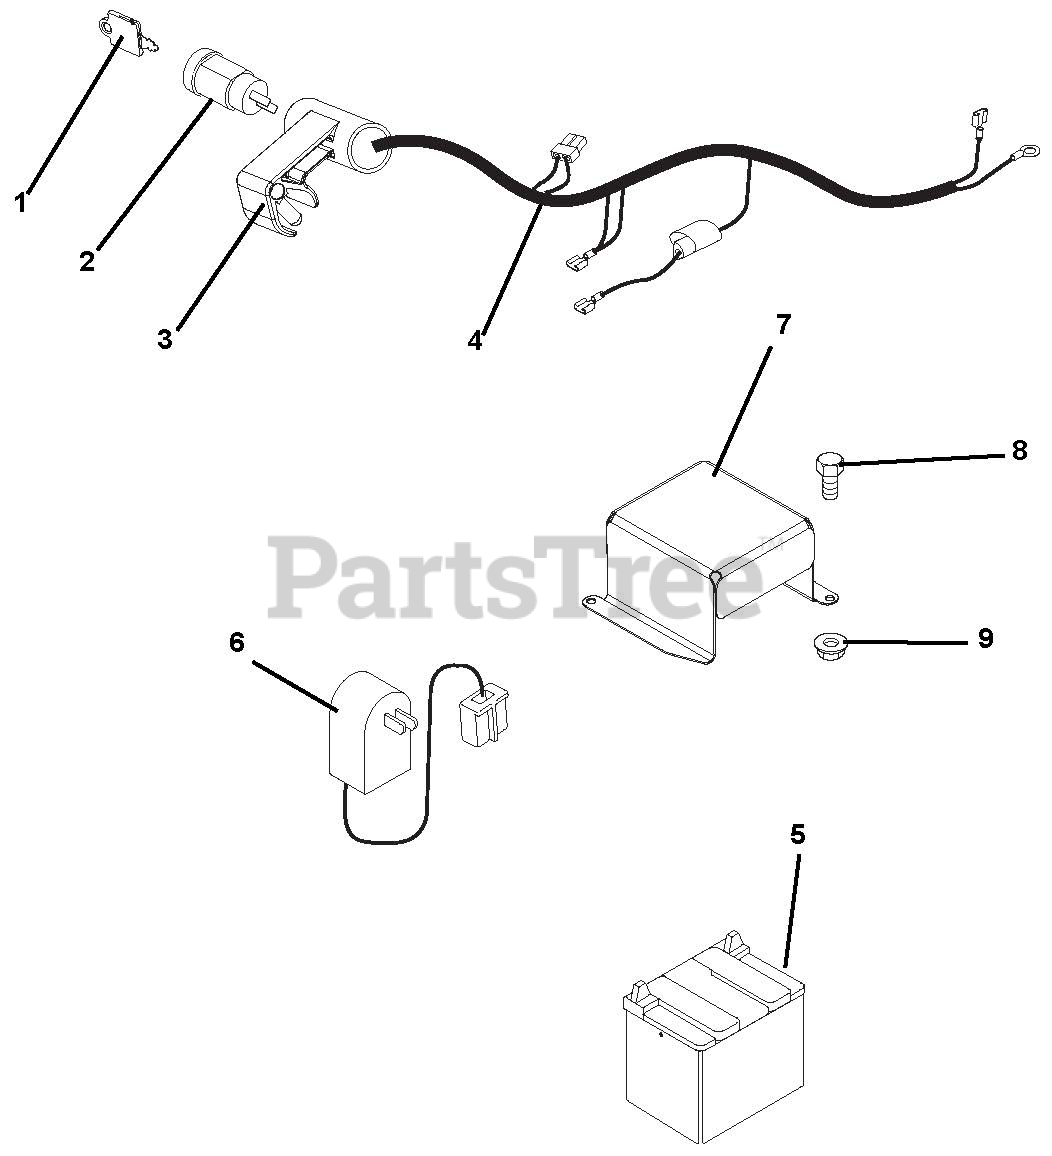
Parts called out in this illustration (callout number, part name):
1	KEY -W/CAP
2	KEYSWITCH
3	SNAP-ON E-START HOUSING
4	HARNESS, BLADE RUNNER WIRE
5	BATTERY - 12V
6	CHARGER, BATTERY
7	COVER, BATTERY
8	@BLT-HEX 8-32 X .5 YWZC
9	@NUT-LK-NYL 8-32 W/INSTR YWZC
